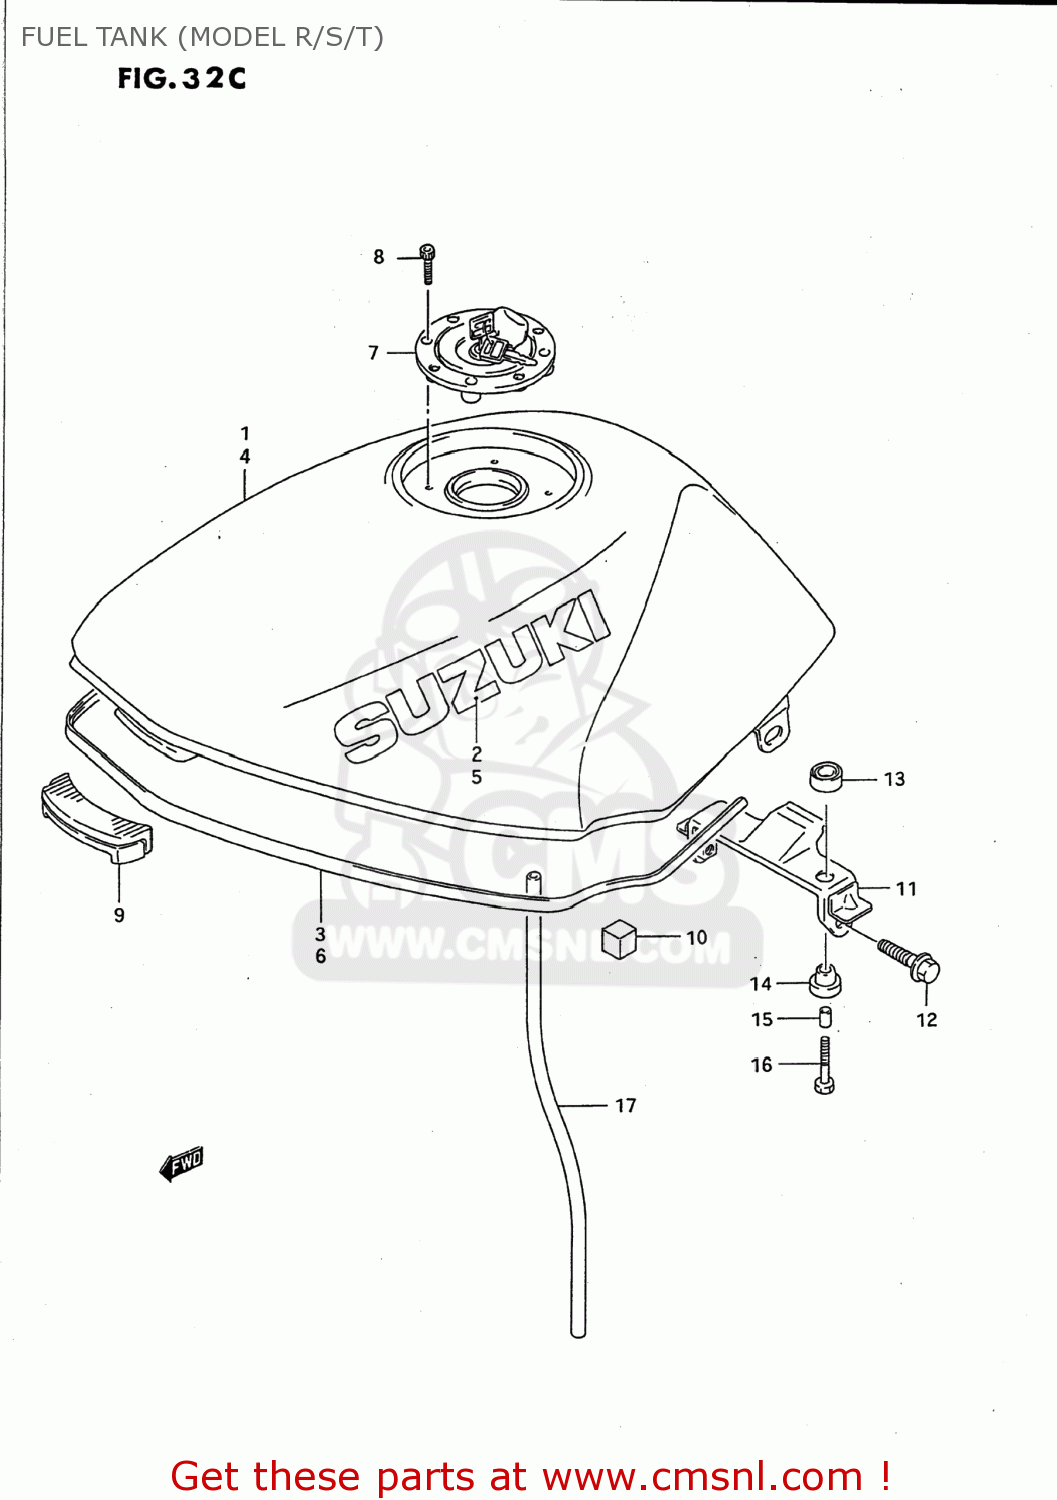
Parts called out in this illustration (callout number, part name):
1	TANK ASSEMBLY,FUEL
2	EMBLEM,FUEL TANK
3	MOLDING
4	TANK ASSEMBLY,FUEL
5	EMBLEM,FUEL TANK
6	MOLDING
7	CAP SET,FUEL TANK
8	BOLT(5X20)
9	CUSHION,FUEL TANK FR
10	CUSHION,FUEL TANK SIDE
11	BRACKET COMP,FUEL TANK
12	BOLT
13	CUSHION
14	CUSHION
15	SPACER
16	BOLT
17	HOSE,WATER DRAIN
